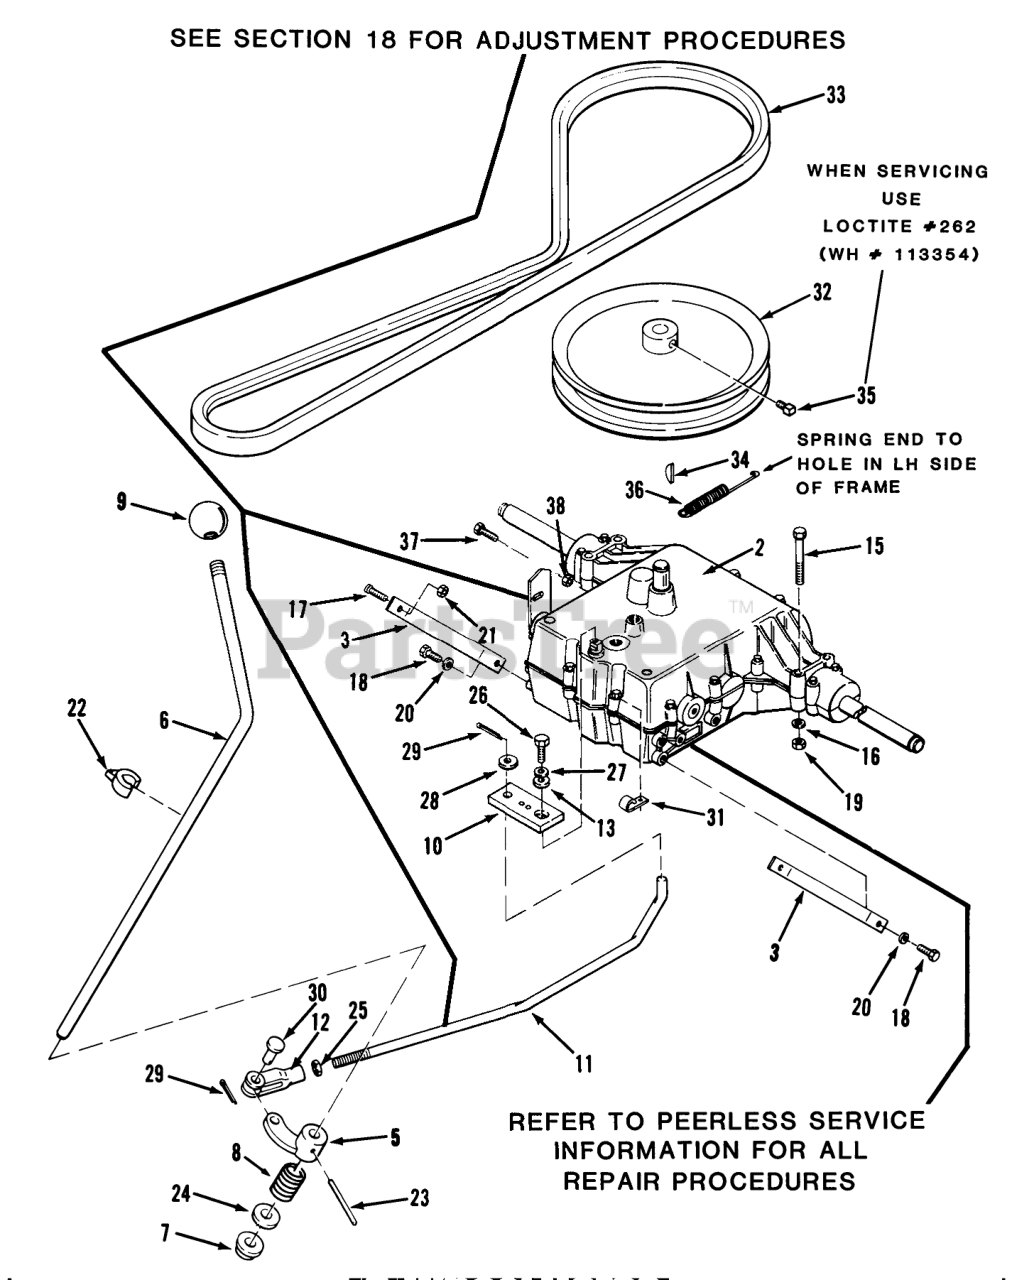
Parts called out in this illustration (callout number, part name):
2	Trans.-4-Spd.(Peerless Model 900-029)
2	Trans.-5-Spd.(Peerless Model 920-009)
2	Trans.-6-Spd.(Peerless Model 920-010)
3	TORQUE-STRAP R
3	TORQUE STRAP R
5	ARM SHIFTER B
6	ROD SHIFT LEVER
7	BUSHING-NYLINER
8	SPRING COMPRESSION
10	ARM-TRANSMISSION R
11	ROD LINKAGE 3SPD
12	CLEVIS
13	WASHER
15	HHCS
16	WASHER 5/16 SAE
17	CARRIAGE BOLT -4
18	Screw
19	Nut
20	Lockwasher
21	Nut
22	POINTER
23	SPIROL PIN 7/32X21/2
24	SHIM-WASHER
24	WASHER
25	Nut
26	Bolt 1/4-28 X 7/8
27	Washer
28	WASHER 5/16 SAE
29	Cotter Pin
31	J-CLIP
32	Transmission Pulley
33	BELT-V
34	KEY-HI-PRO
35	Set Screw
36	SPRING-EXTENSION
37	Bolt
38	Nut
